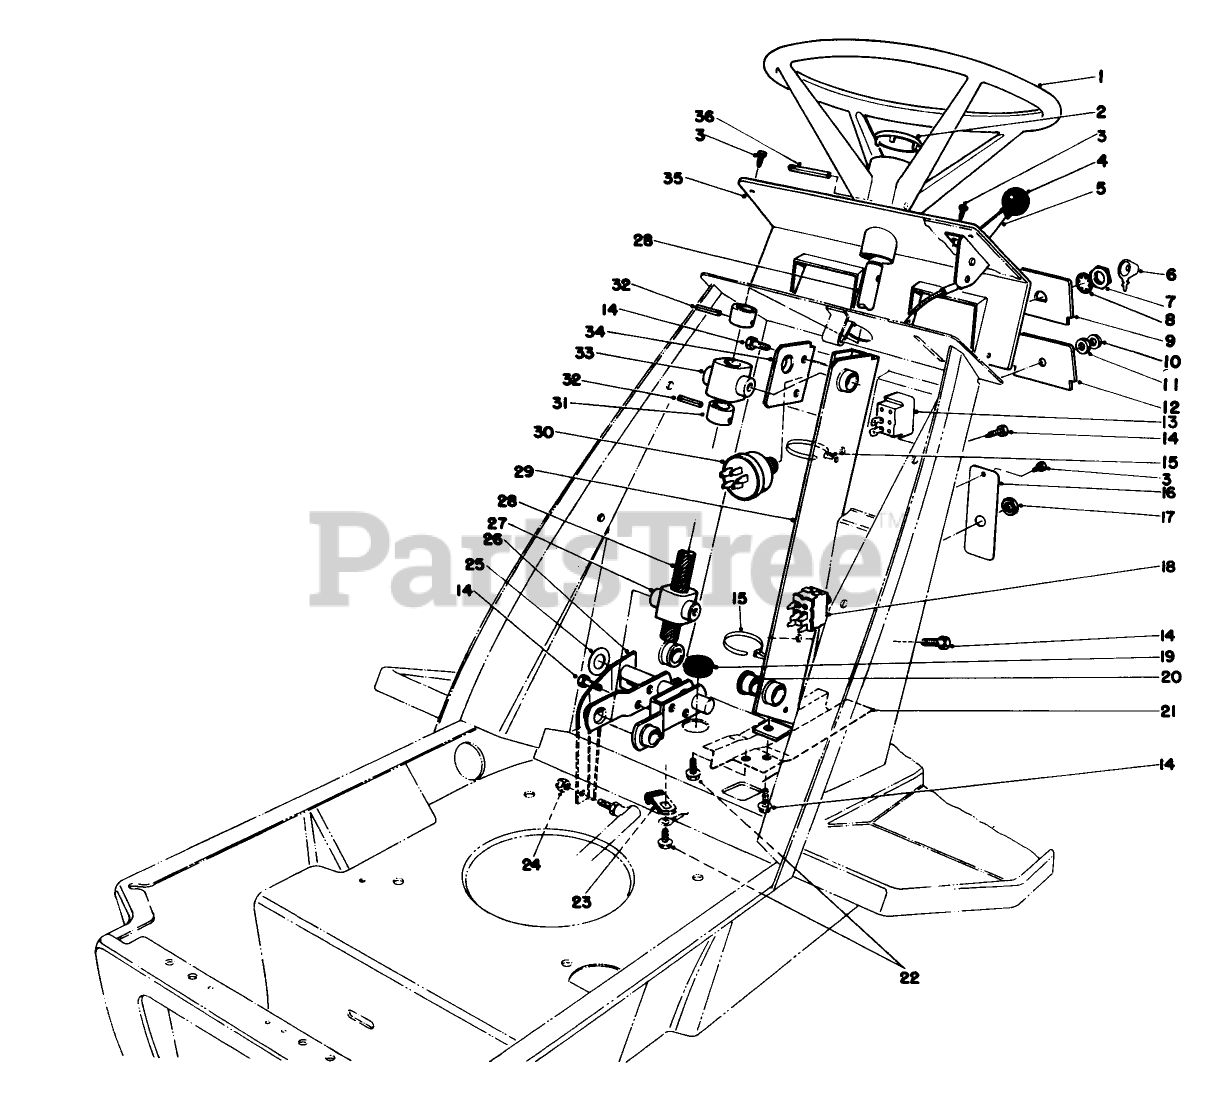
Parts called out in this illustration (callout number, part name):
1	STEERING WHEEL ASM
3	SCREW-HWHTF
4	KNOB-CONTROL
5	THROTTLE CONTROL
7	NUT-HH
8	WASHER-LOCK
11	NUT-LOCK
13	SWITCH-LIGHT
14	SCREW-THD ROLL, HWH
15	TIE-CABLE
19	GROMMET
20	BEARING-FLANGE
22	SCREW
23	CLIP-FUEL LINE
24	NUT-HEX
28	STEERING SHAFT
30	SWITCH-STARTER
31	STRG SHAFT COLLAR
32	PIN-SPRING
36	PIN-ROLL
